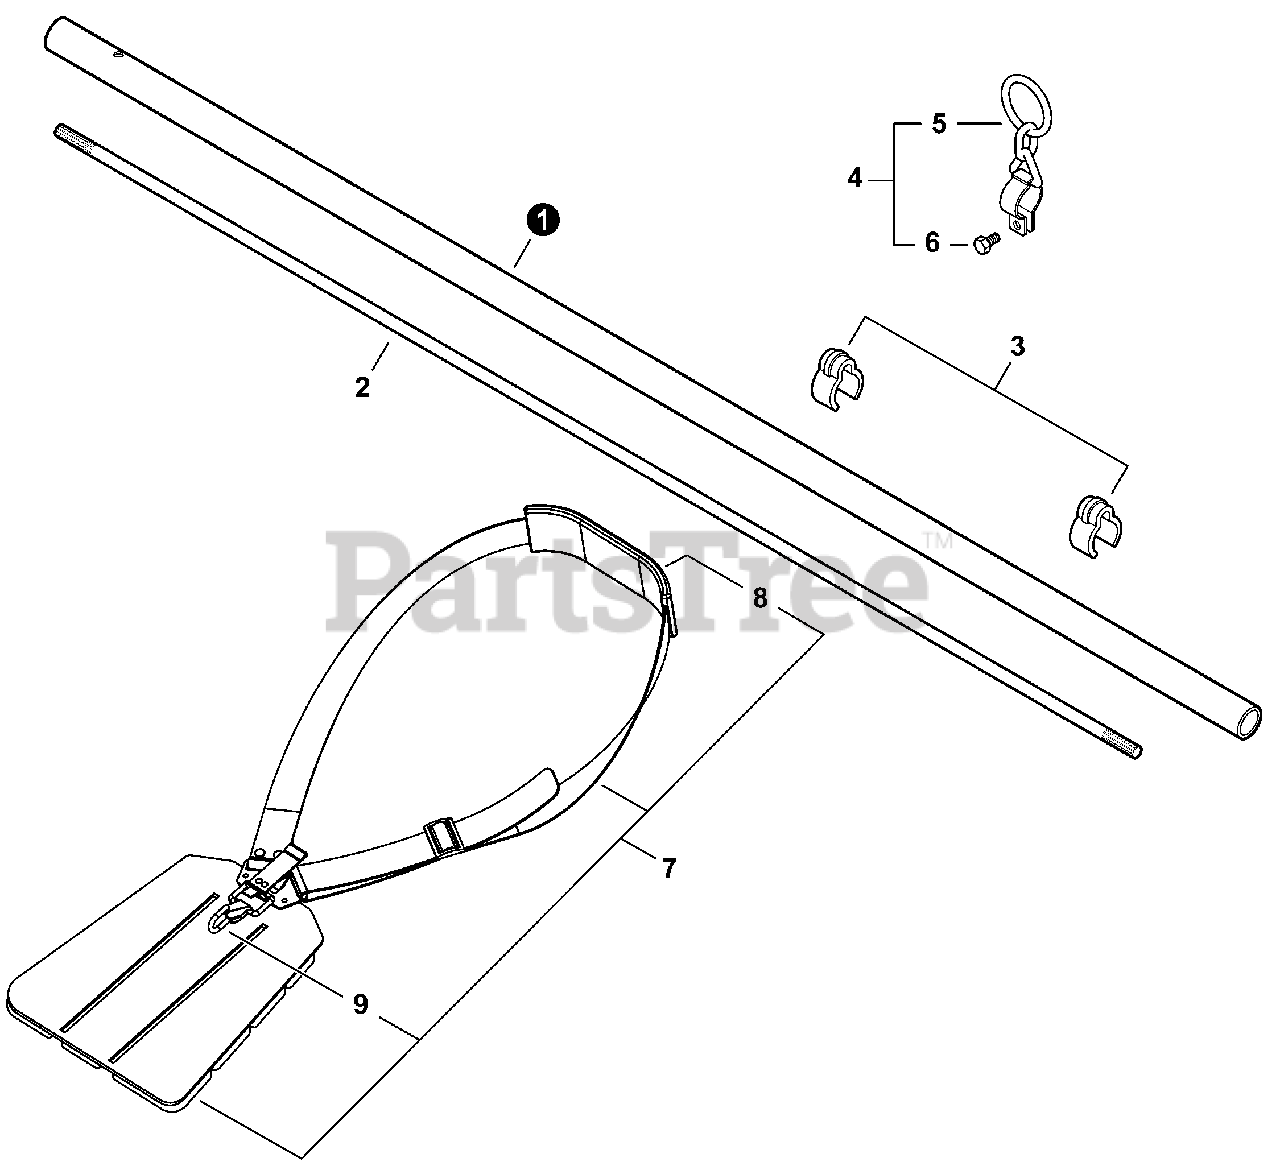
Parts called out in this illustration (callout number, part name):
1	PIPE, MAIN
2	MAINSHAFT
3	CLIP, CABLE 25MM
4	HANGER SET, HARNESS
5	HANGER, HARNESS
6	BOLT 5×12
7	HARNESS ASSY, BRUSHCUTTER
8	PAD, SHOULDER
9	HOOK, SNAP
